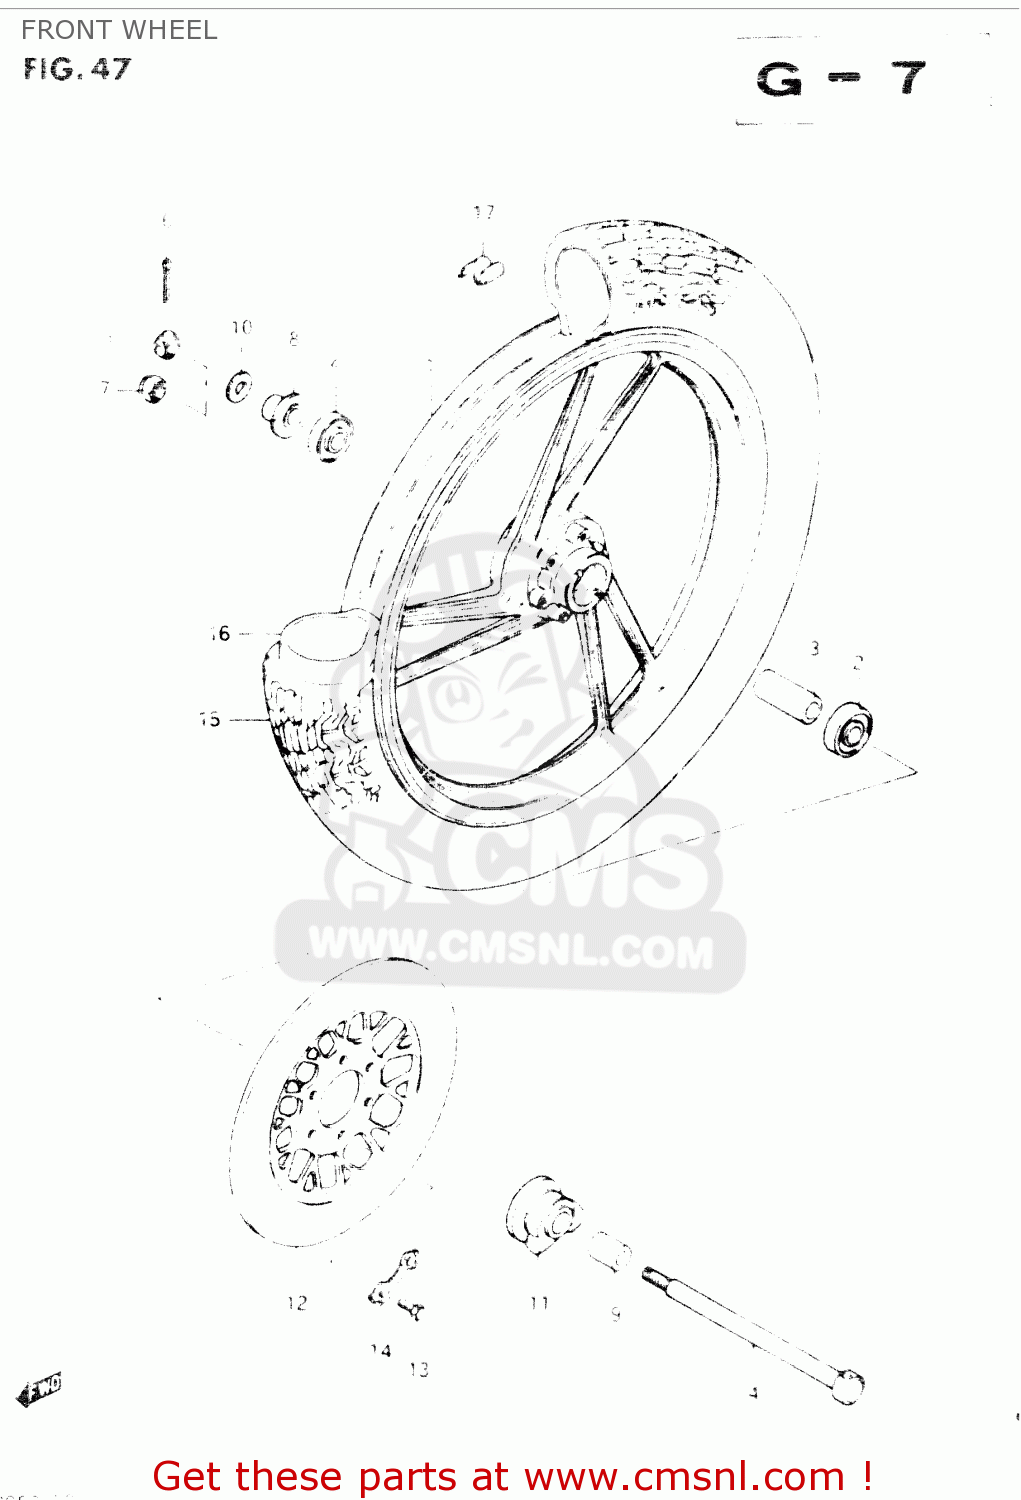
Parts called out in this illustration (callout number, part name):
1	WHEEL (1.60X18)
2	BEARING
3	SPACER(15.3X21.7X63)
4	AXLE,FRONT
5	NUT 12MM
6	COTTER PIN
7	NUT
8	SPACER,FR HUB BEARING,R
9	SPACER(15X22X30)
10	WASHER
11	BOX ASSEMBLY,SPEEDOMETER GEAR
12	DISC,FR BRAKE
13	BOLT(8X25)
14	WASHER
15	TIRE,FRONT
16	TUBE,INNER
17	BALANCER,WHEEL
